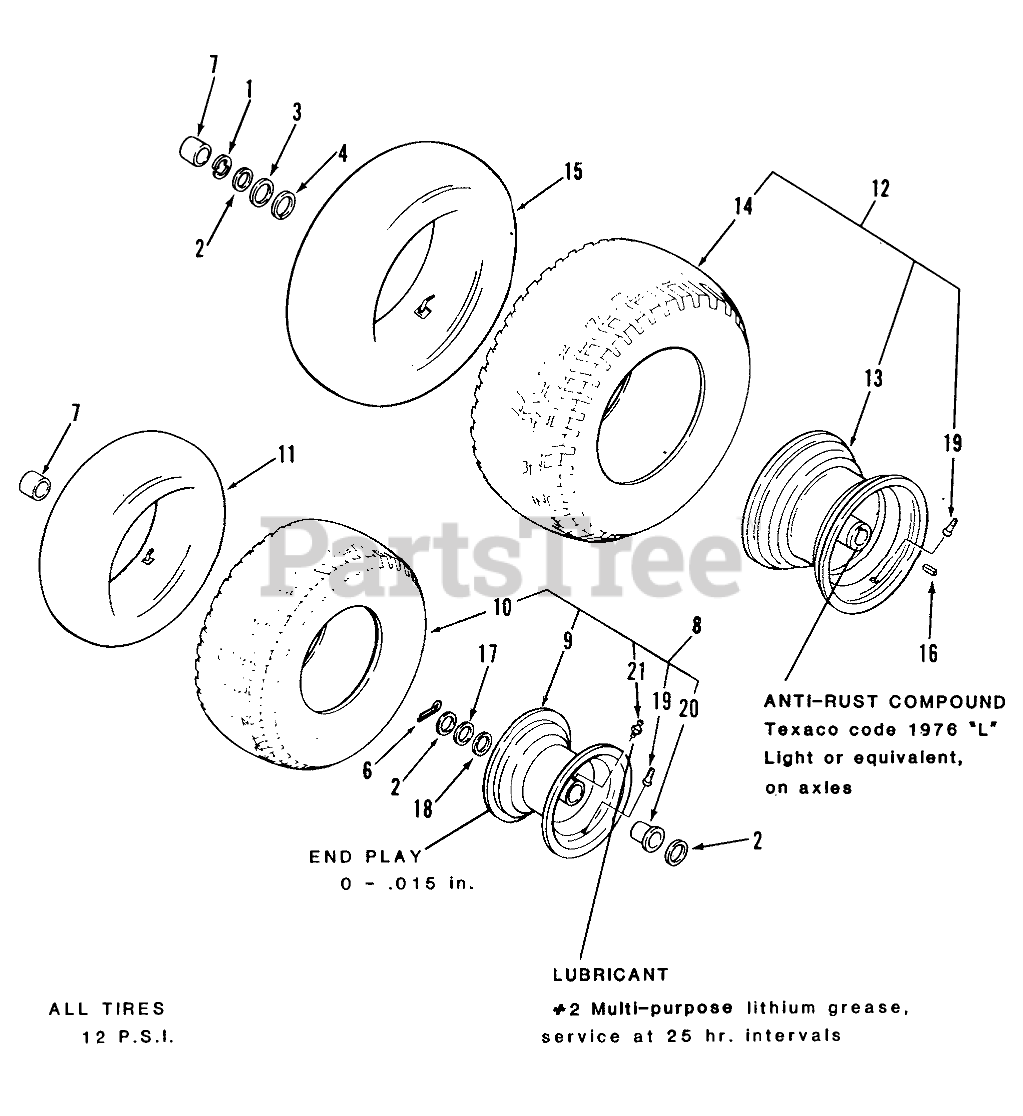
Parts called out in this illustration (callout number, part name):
1	E Ring
2	WASHER-FLAT
3	WASHER-SHIM
4	WASHER
6	COTTER PIN-4
7	HUB CAP-FLAT BLACK
8	Assy-Wheel & Tire Front 5-Speed
9	ASSY WHEEL
11	Tube (Service Only)
12	Assy-Wheel & Tire-Rear-5-Speed 227-5
13	ASSY WHEEL RIM
14	Rear Tire 20 x 10.0-10.0
15	Rear Tube-Service Only-5-Speed
16	SQ KEY
17	WASHER
18	WASHER-SHIM
19	VALVE
20	FLANGE BEARING
21	Zerk
